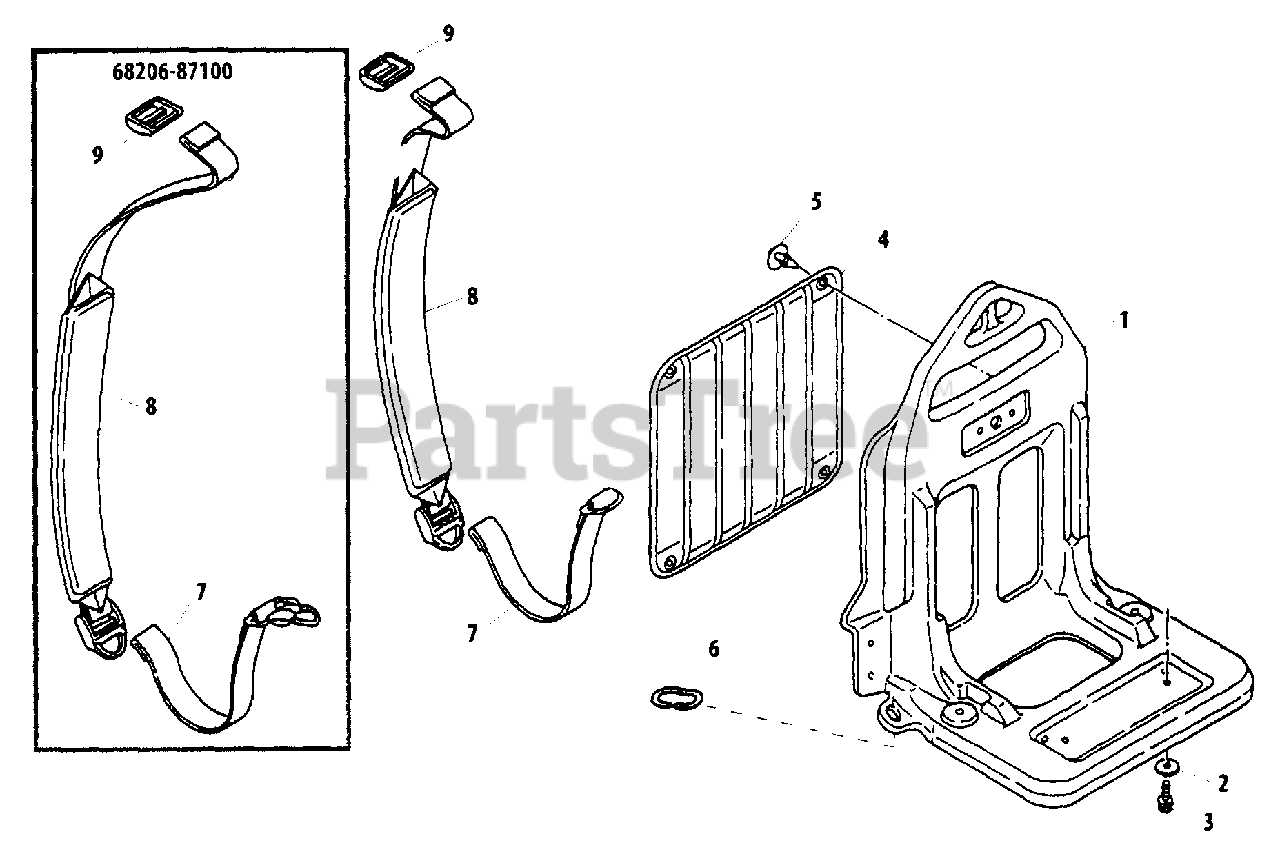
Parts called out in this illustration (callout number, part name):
1	FRAME
2	COLLAR
3	SCREW - 5X14
4	PAD
5	CLIP
6	HOOK, SPRING
7	STRAP
8	STRAP, BACKPACK
9	BUCKLE
68206-87100	STRAP ASSY
